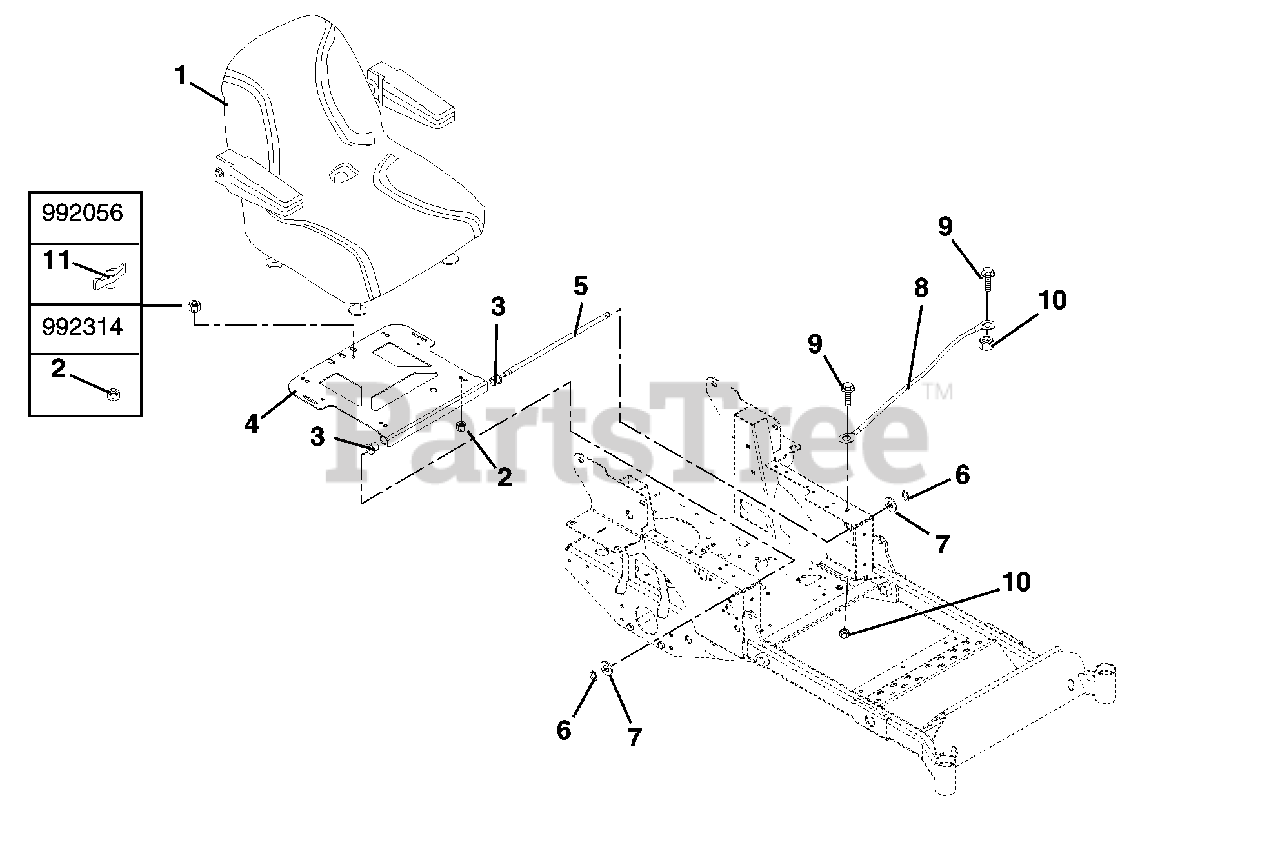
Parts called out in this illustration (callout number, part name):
1	Seat
2	Nut, Locking Top Flange .31-18 (314)
2	Nut, Locking Top Flange .31-18 (056)
3	Bushing, Flange .515 x .750 x .745 x 1.00
4	Seat Pivot Mount
5	Rod, Seat Frame Pivot
6	Ring, Retaining External .50 x .05
7	Washer, Flat Steel .531 x 1.06 x .095
8	Cable, Hood
9	Bolt, Hex .25-20 x .75 Grade 5
10	Nut, Locking Top Flange .25-20
11	Knob, Wing .312-18 (056)
